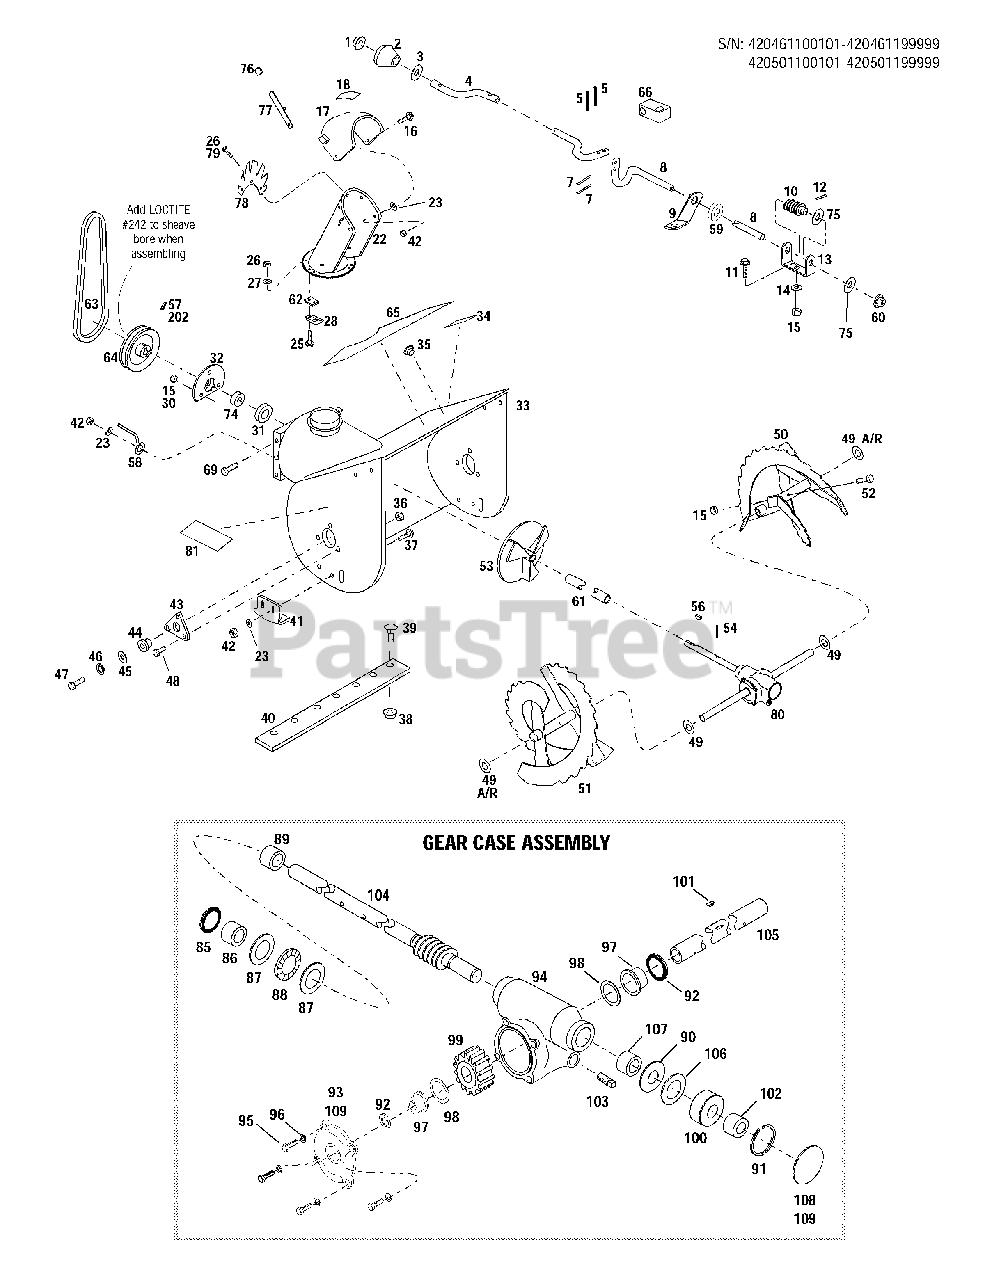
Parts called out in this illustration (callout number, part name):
1	Push-On Cap
2	Knob
3	Flat Washer, 3/8
4	Chute Control Crank
5	Cotter Pin, 3/32 x 5/8
7	Roll Pin, 1/8 x 3/4
8	Chute Control Shaft
9	Crank Support
10	Worm Gear
11	Hex Flange Screw, 5/16-18 x 3/4
12	Drive Pin, 3/32 x 3/4
13	Gear Support
14	Flat Washer, 5/16
15	Locknut, 5/16-18
16	Hex hd. Screw, 3/8-16 x 3/4
17	Cap Assembly
18	Warning Decal
23	Flat Washer, 3/8
25	Sems Screw , #10-24 x 7/8
26	Locknut, #10-24
27	Flat Washer, #10
28	Hold Down Clip
30	Hex hd. Screw, 5/16-18 x 5/8
31	Ball Bearing
32	Bearing Retainer
33	Collector (auger/impeller) Housing Assembly
34	Warning Decal
36	Locknut,1/4-20
37	Carriage Bolt, 3/8-16 x 3/4
38	Flange Locknut, 5/16-18
39	Carriage Bolt, 5/16-18 x 1/2
40	Scraper Blade
41	Skid Shoe
42	Locknut, 3/8-16
43	Support Bearing
44	Flange Bushing
45	Flat Washer, 1/2
46	Lockwasher, 1/2
47	Hex Hd. Screw, 1/2-13 x 3/4
48	Hex Hd. Screw, 1/4-20 x 5/8
49	Special Washer
50	Left Auger Blade
51	Right Auger Blade
52	Shear Bolt, 5/16-18
53	Impeller
54	Roll Pin, 1/4 x 1-1/4
56	Key, 3/16 x 3/4
57	Square Set Screw, 5/16-18 x 5/8
58	Belt Guide
59	Nylon Bushing
60	Flange Nut
61	Sleeve
64	Auger Sheave
65	Logo Decal
66	Swivel Block
69	Hex Flange Screw, 5/16-18 x 3/4
74	Shim Washer
75	Nylon Washer
77	Adjusting Lever
78	Chute Deflector
79	Truss Head Bolt, 10-24
80	Gear Case Assembly
81	Logo Decal
86	Needle Bearing
87	Thrust Race
88	Thrust Bearing
90	Washer
91	Internal Retaining Ring
92	Oil Seal
93	Gear Case Cover
94	Gear Case (case only)
95	Screw, 1/4-20 x 5/8
96	Lockwasher, 1/4
97	Flange Bearing
98	Thrust Race
99	Worm Gear, 20T
100	Spacer
101	Woodruff Key, 1/4 x 7/8
102	Needle Bearing
103	Pipe Plug, 1/4-18
104	Impeller Shaft
105	Auger Shaft
106	Thrust Race
107	Spacer
108	Welsh Plug
109	Sealant
